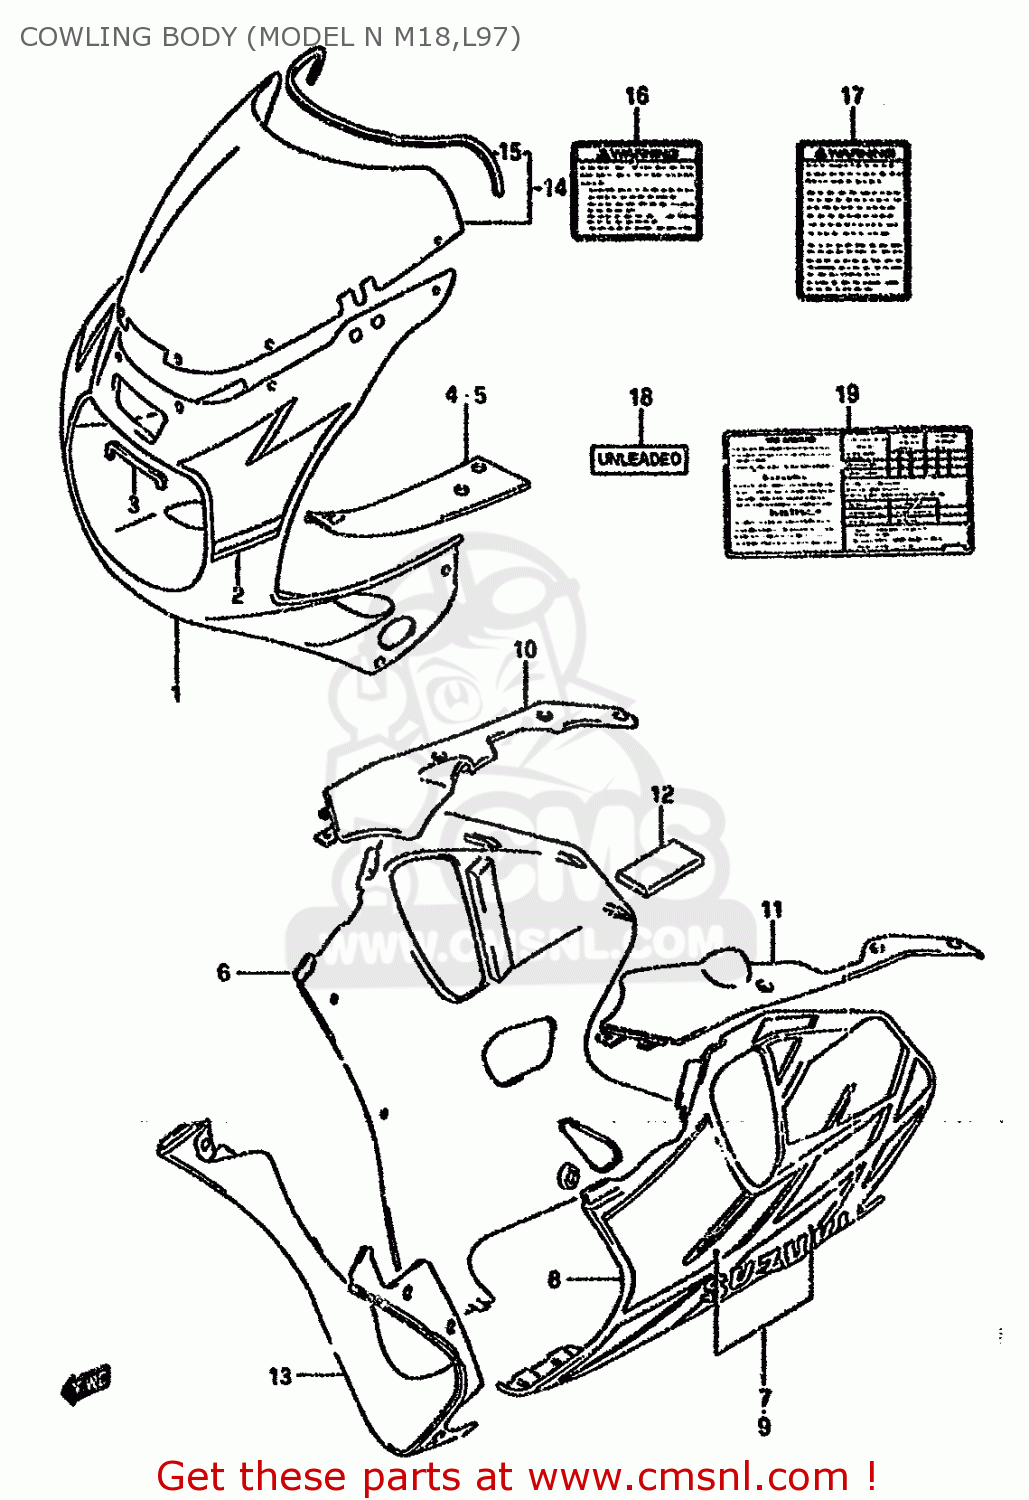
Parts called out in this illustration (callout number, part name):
1	COWLING ASSY,BODY
2	TAPE SET,UPPER
3	CUSHION,FR POSITION LAMP
4	PANEL,UPR,R
5	PANEL,UPR,L
6	COWLING ASSY,UNDER,R
7	TAPE SET,UNDER RH
8	COWLING,UNDER,
9	TAPE SET,COWL UNDER,L
10	PANEL,LWR,R
11	PANEL,LWR,L
12	CUSHION,PANEL
13	COWLING,UNDER CTR
14	WINDSCREEN SET
15	MOLDING
16	LABEL, WARNING SAFETY
17	LABEL (WARNING SCREEN)
18	LABEL,CAUTION
19	LABEL,TIRE AIR PRESSURE
